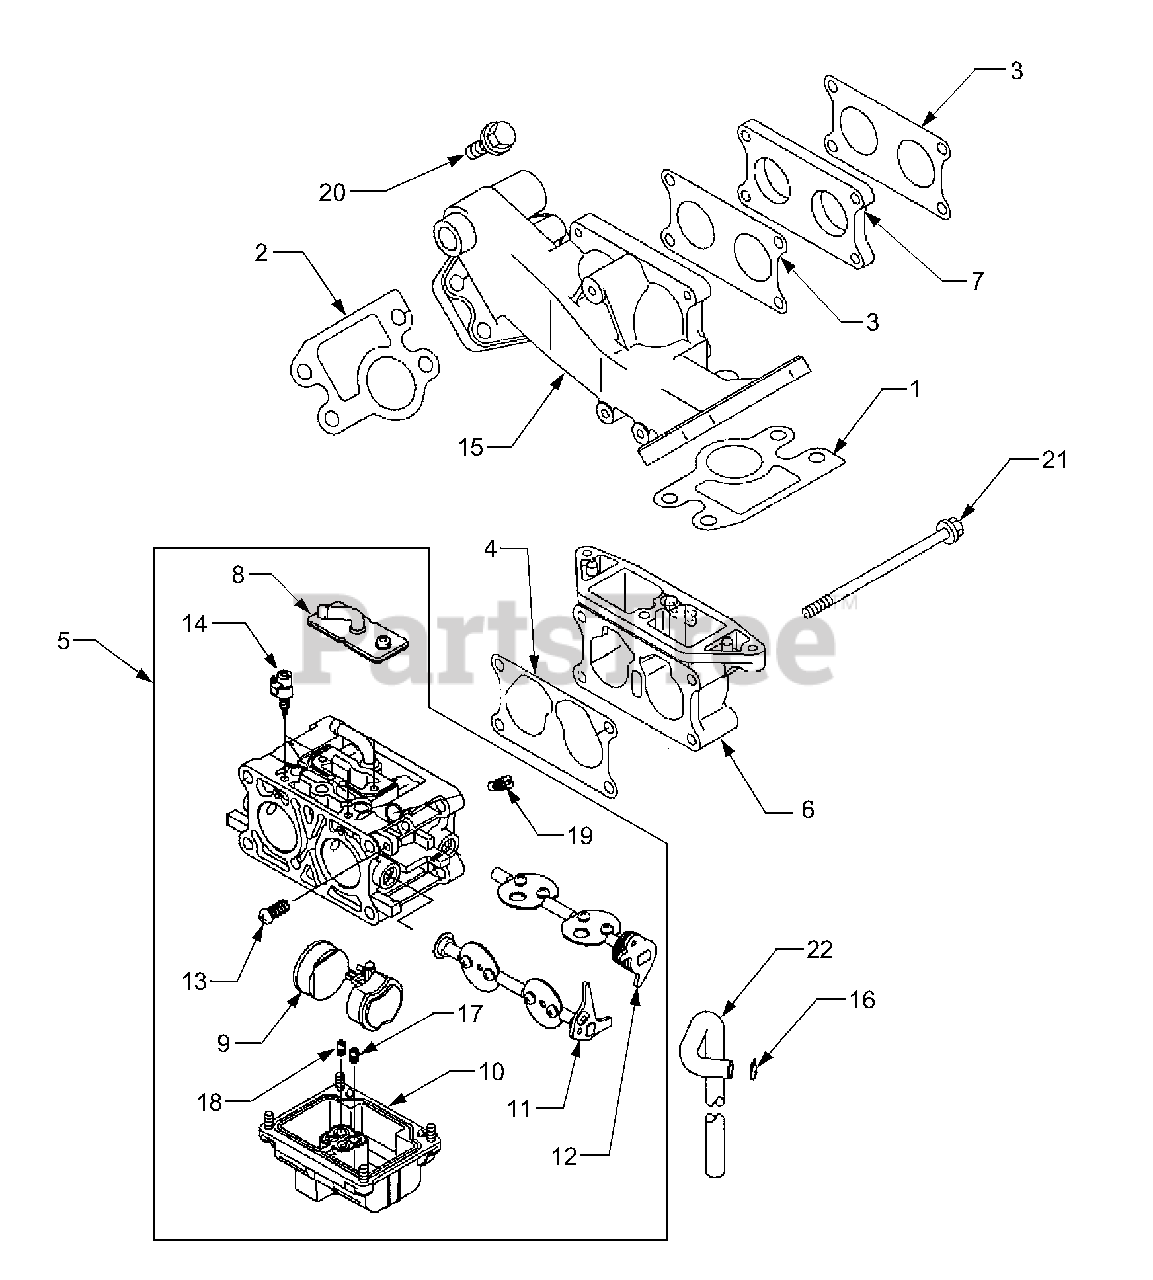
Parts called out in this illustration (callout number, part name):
1	Gasket, Intake Manifold
2	Gasket, Intake Manifold
3	Gasket, Intake Pipe
5	Carburetor Assembly
8	Cover Assembly
9	Float Assembly
10	Chamber, Float
11	Valve Assembly, Throttle
12	Valve Assembly, Choke
13	Screw Assembly
14	Screw Assembly
15	Manifold, Intake
17	Jet, Main, #110
18	Jet, Main, #111.3
19	Jet, Pilot, #45
20	Bolt, Flanged
21	Bolt, Flanged
